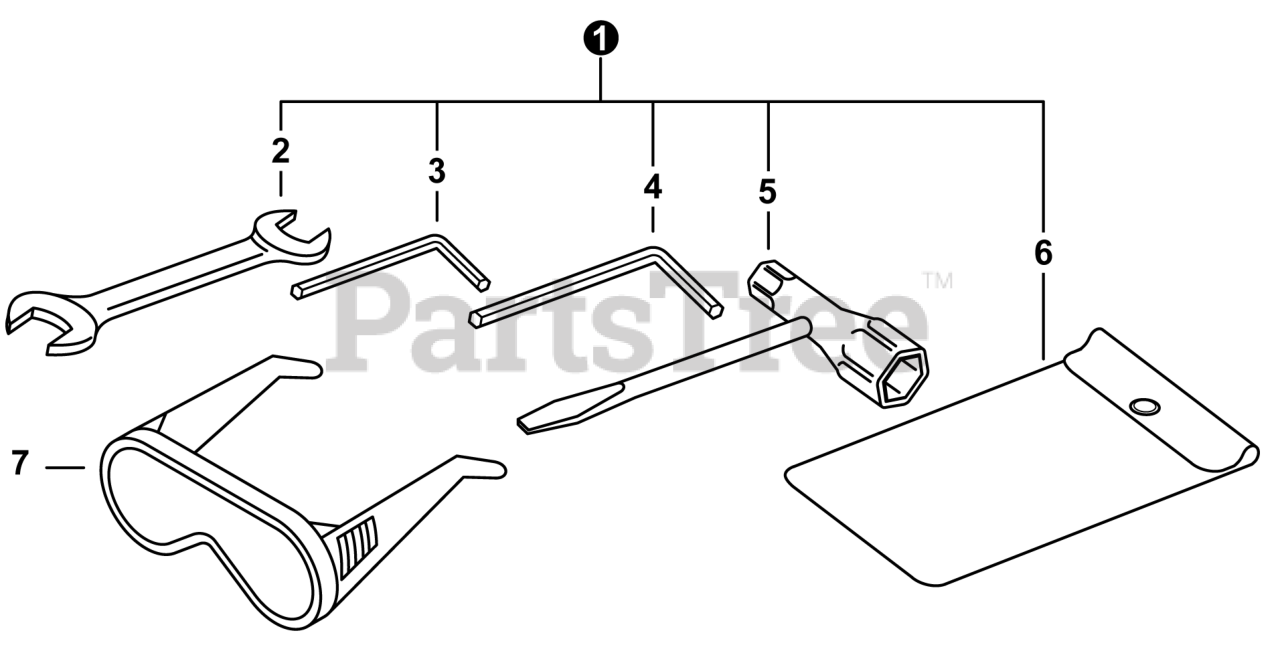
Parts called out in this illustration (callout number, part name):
1	TOOL KIT, SERVICE
2	SPANNER 8x10
3	WRENCH, ALLEN 4 MM
4	WRENCH, ALLEN 5 MM
5	T-WRENCH 17x19 L200
6	BAG, TOOL
7	GLASSES, SAFETY
